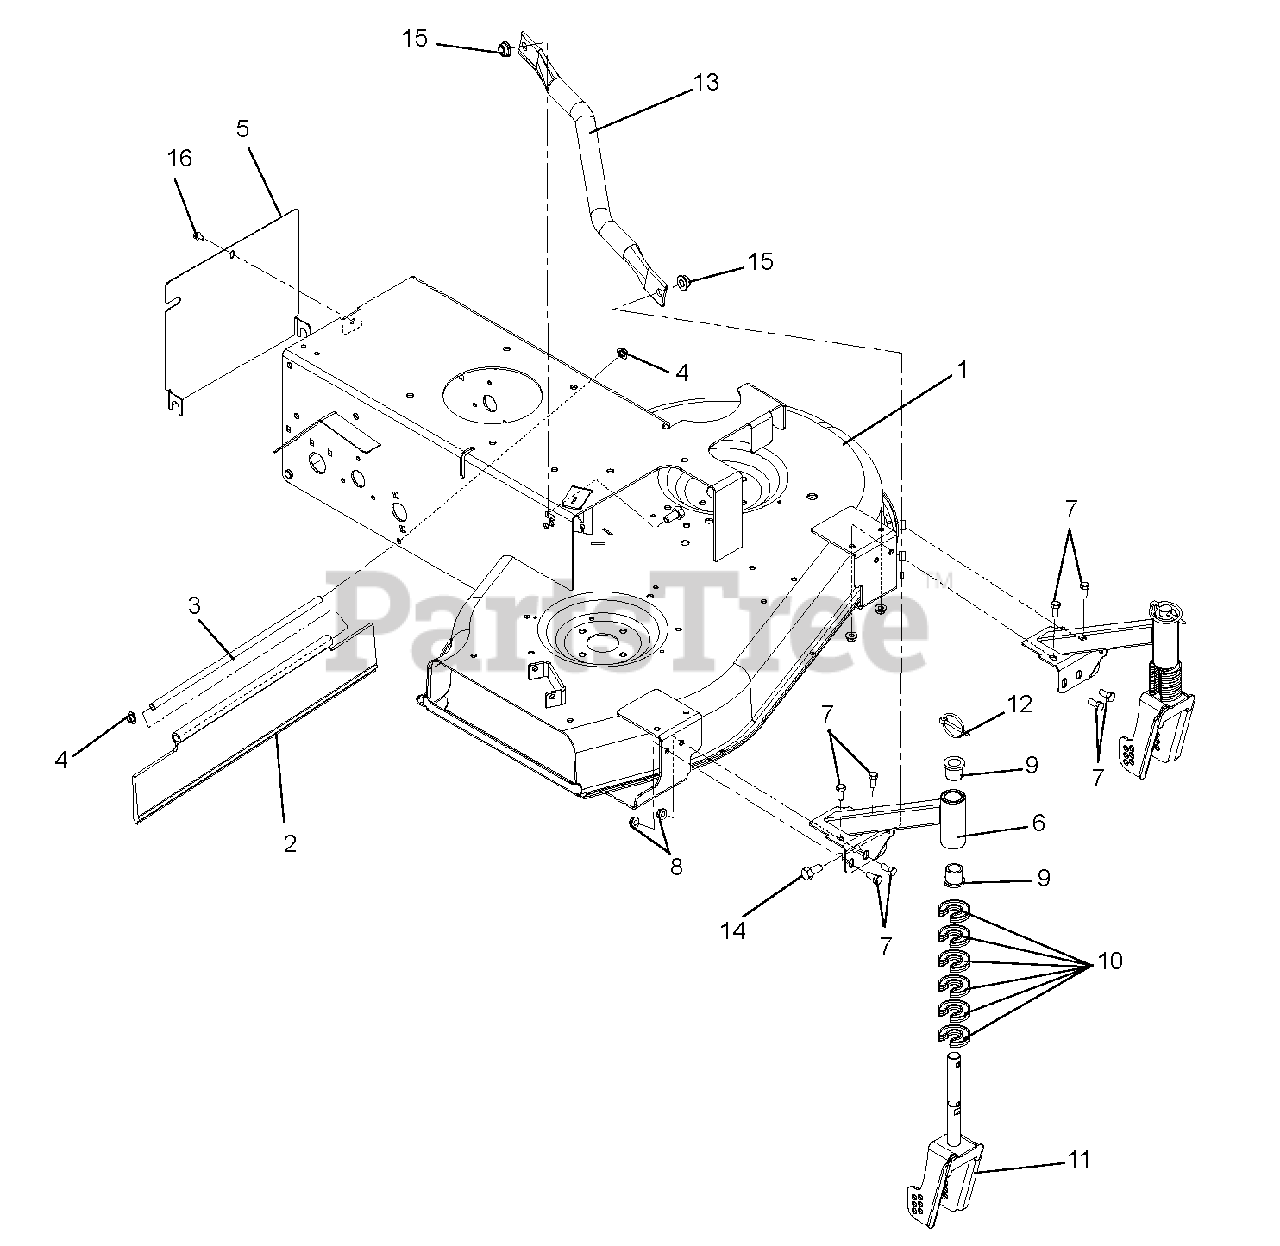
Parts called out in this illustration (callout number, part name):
1	Chassis, Wide Area Walk CE
2	Guard, Rear Swivel
3	Rod, Trailing Shield
4	Nut, Push .312 Dia. PAL
5	Cover, Rear Chassis
6	Weldment, Caster Arm
7	Bolt, Hex .31-18 x .75
8	Nut, Locking Top Flange .31-18
9	Bushing, Flange .75 x .75 x 1.0
10	Clip, HOC Fixed
11	Fork, WAW Caster
12	Pin, Lynch .25 x 1.25
13	Strap, Frame Reinforcing
14	Bolt, Hex .38-16 x .75
15	Nut, Locking Top Flange .38-16
16	Screw, Tapping .25-20 x .50
